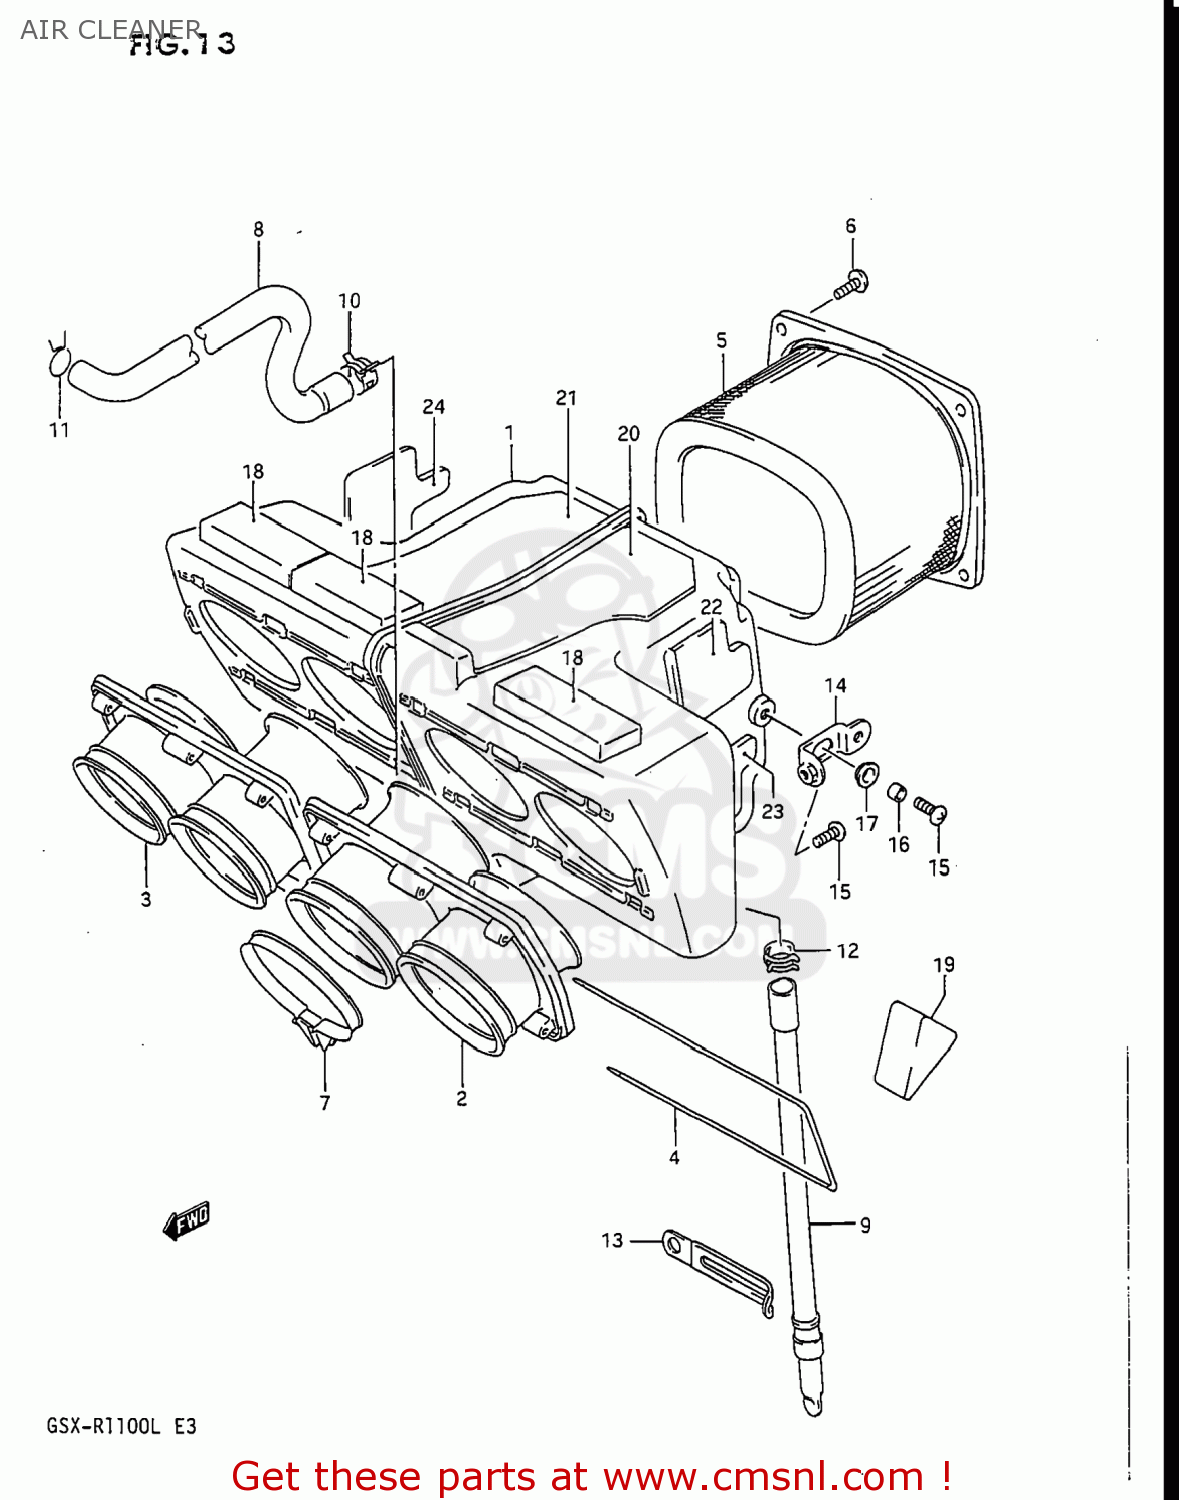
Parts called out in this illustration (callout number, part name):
1	CASE,AIR CLEANER
2	TUBE,AIR CLEANER OUTLET LH
3	TUBE,OUTLET,R
4	SHAFT,OUTLET TUBE
5	FILTER ASSY,AIR CLEANER
6	SCREW
7	CLAMP
8	TUBE,BREATHER
9	DRAIN TUBE
10	CLIP
11	CLIP
12	CLIP
13	CLAMP
14	BRACKET,AIR CLEANER CASE
15	SCREW
16	SPACER
17	WASHER
18	CUSHION,AIR CLEANER CASE
19	CUSHION,AIR VENT HOSE
20	SHEET,AIR CLEANER NO.1
21	SHEET,AIR CLEANER NO.2
22	SHEET,AIR CLEANER NO.3
23	SHEET,AIR CLEANER NO.4
24	SHEET,AIR CLEANER NO.5
